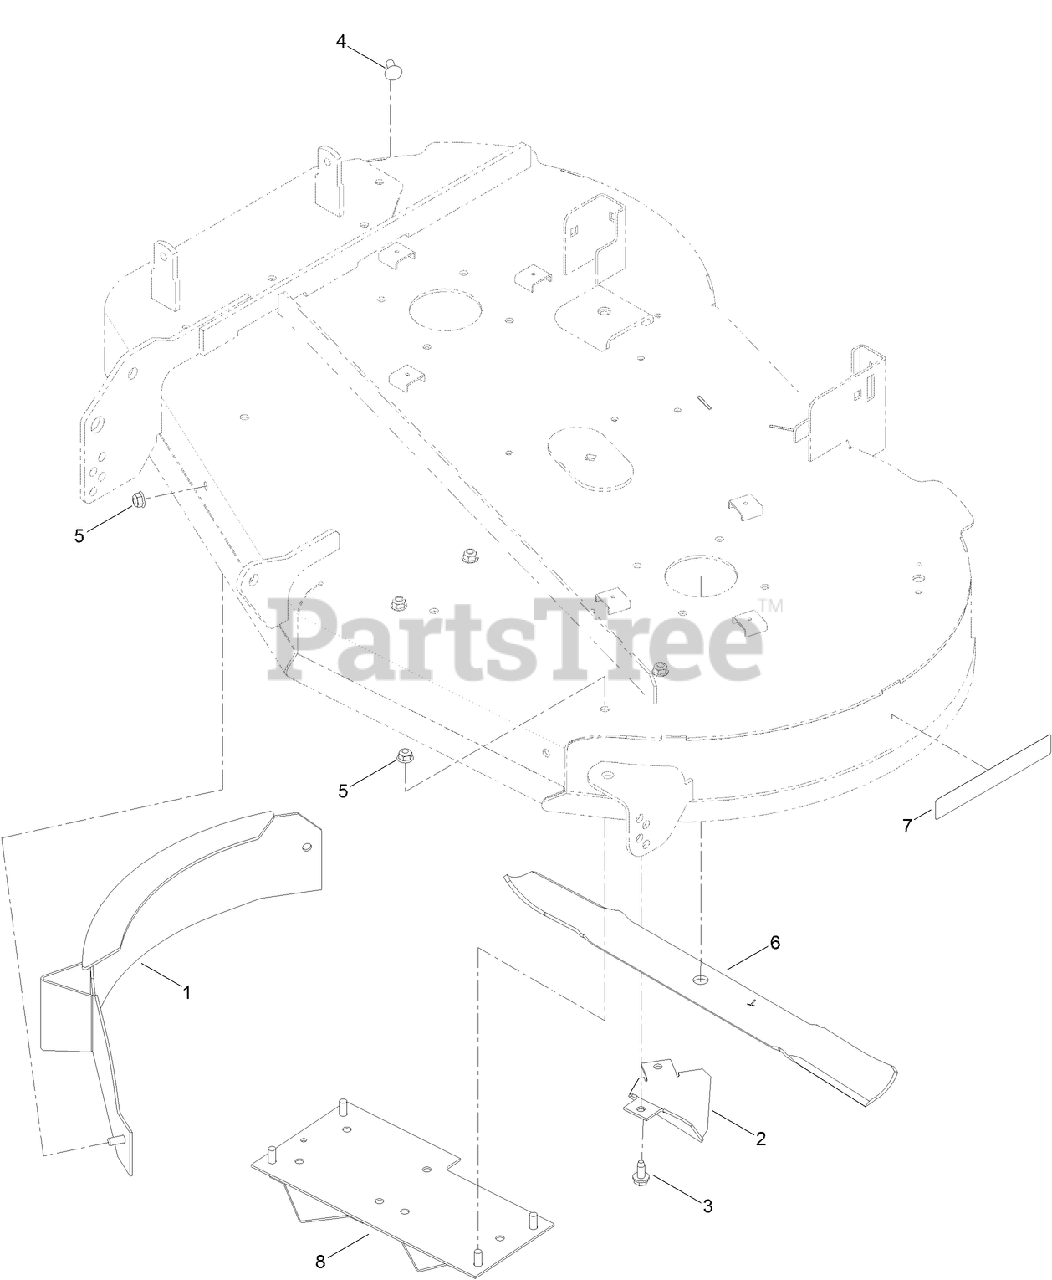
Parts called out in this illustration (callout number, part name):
1	BAFFLE ASM
2	KICKER-FLANGED
3	SCREW-HWHTF
4	BOLT-CARR
5	NUT-HF, NI
7	DECAL-RECYCLER
8	KICKER ASM
